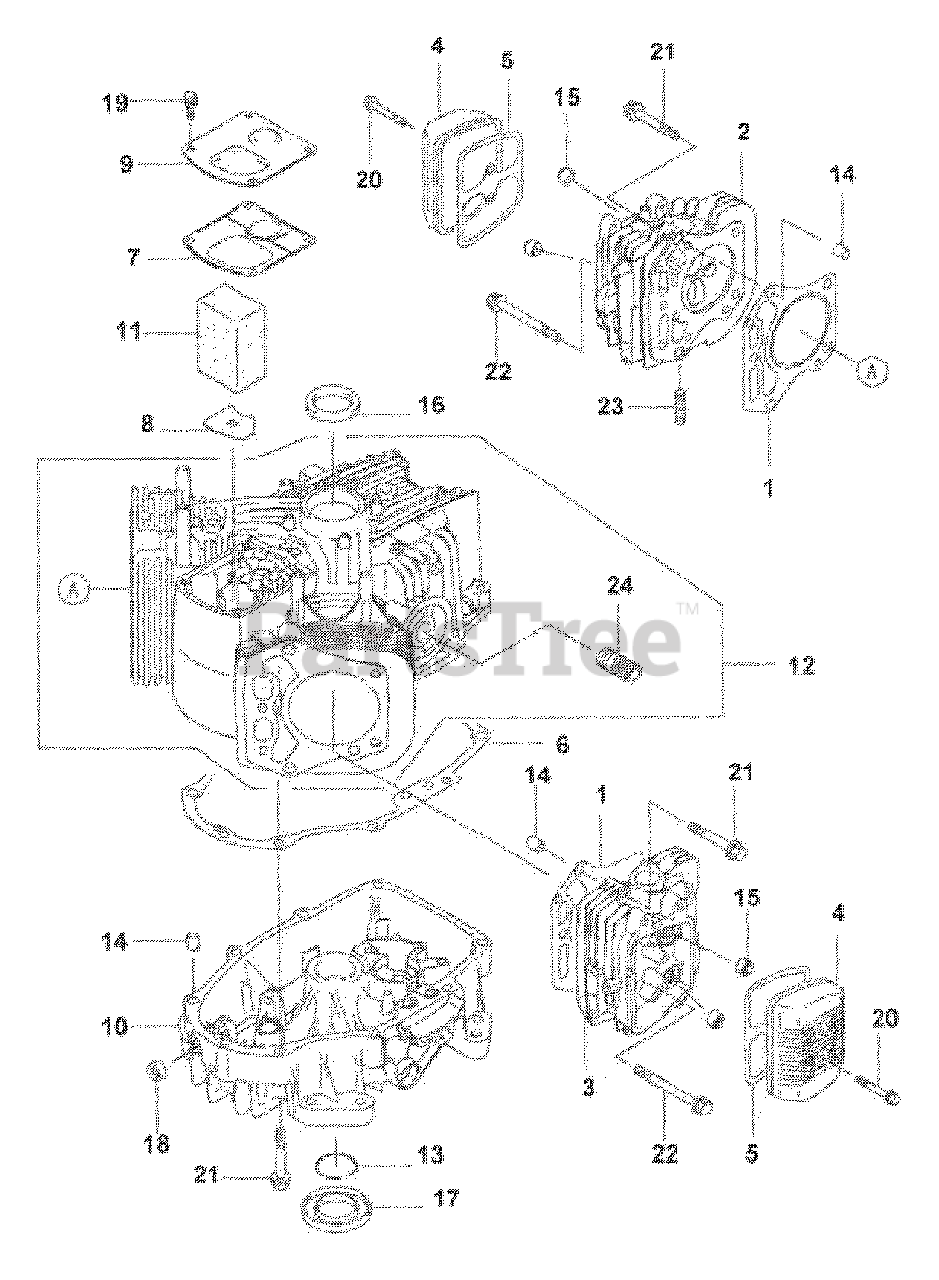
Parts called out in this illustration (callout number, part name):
1	Head Gasket
2	Cylinder Head #1
3	Cylinder Head #2
5	Rocker Case Gasket
6	Crankcase Gasket
7	Breather Gasket
9	Breather Cover
10	Crankcase Cover
11	Breather Element
12	Crankcase Complete
15	Oil Seal
16	Oil Seal 35X48X8
17	Oil Seal 35X62X8
18	Oil Seal
19	Flange Bolt
20	Flange Bolt
21	Flange Bolt
22	Flange Bolt
23	Stud Bolt
